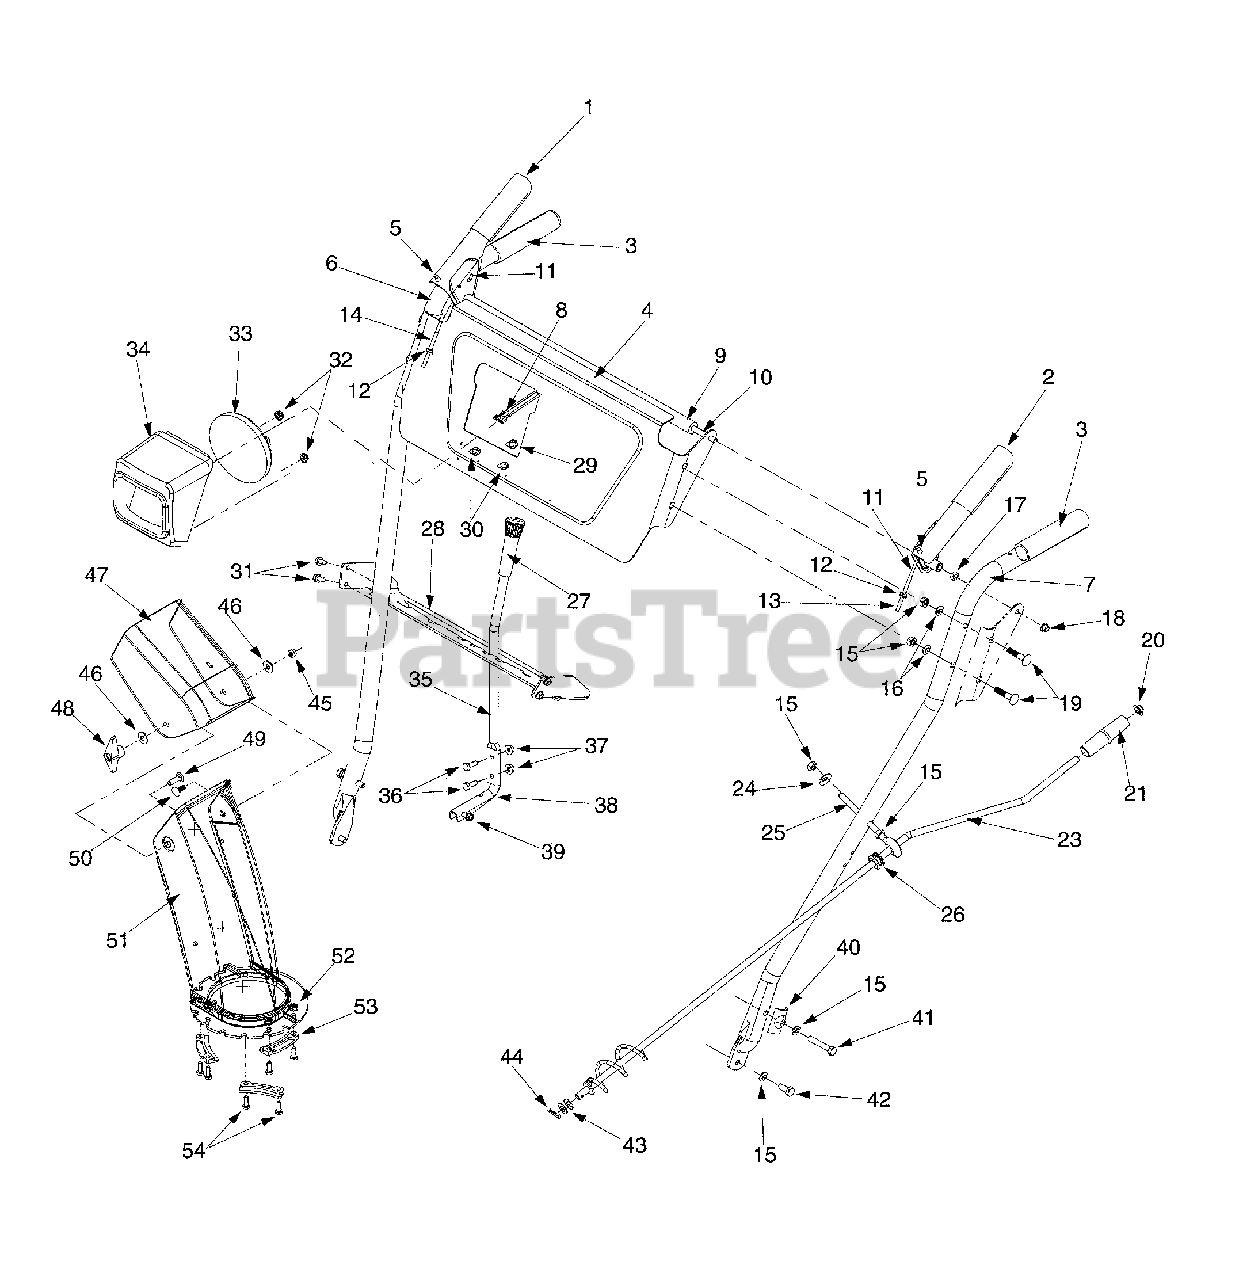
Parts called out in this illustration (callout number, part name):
1	Clutch Lever Assembly - RH
2	Clutch Lever Assembly - LH
5	Bumper Rubber
9	Pivot Rod Cover
10	Pivot Rod
11	"Z" Fitting
12	Hex Nut
13	Auger Clutch Cable
14	Drive Clutch Cable
15	Hex Nut 5/16-18
16	Lock Washer 5/16
17	Spacer
18	Nut Cap
19	Carriage Bolt 5/16-18 x 1.5
20	Push Rod Cap
21	Chute Crank Knob
23	Chute Crank Assembly
24	Bell Washer.340 ID x .873 OD
25	Eyebolt
26	Rubber Grommet
29	Hex Washer Screw 1/4-20 x .625
30	Hex Washer Screw #10 16 x .625
31	Hex Washer Screw 1/4-20 x .50
32	Hex Nut
33	Headlight 18 Watt
34	Headlight Cover
36	Hex Cap Screw 1 /4-20 x .75
37	Hex Lock Nut 1/4-20
38	Shift Lever Support
39	Hex Washer
40	Handle Tab
41	Hex Cap Screw 5/16-18 x 1.75
42	Hex Cap Screw 5/16-18 x .75
43	Flat Washer 3/8 ID x .738 OD
44	Cotter Pin
45	Hex Lock Nut 5/16-18
46	Washer 5/16
47	Upper Chute
48	Knob 5/16-18
49	Carriage Screw 5/16-18 x 1.0
50	Carriage Bolt 5/16-18 x .75
51	Lower Chute
52	Hex Lock Nut 1/4-20
53	Chute Flange Keeper
54	Hex Cap Screw 1/4-20 x .75
